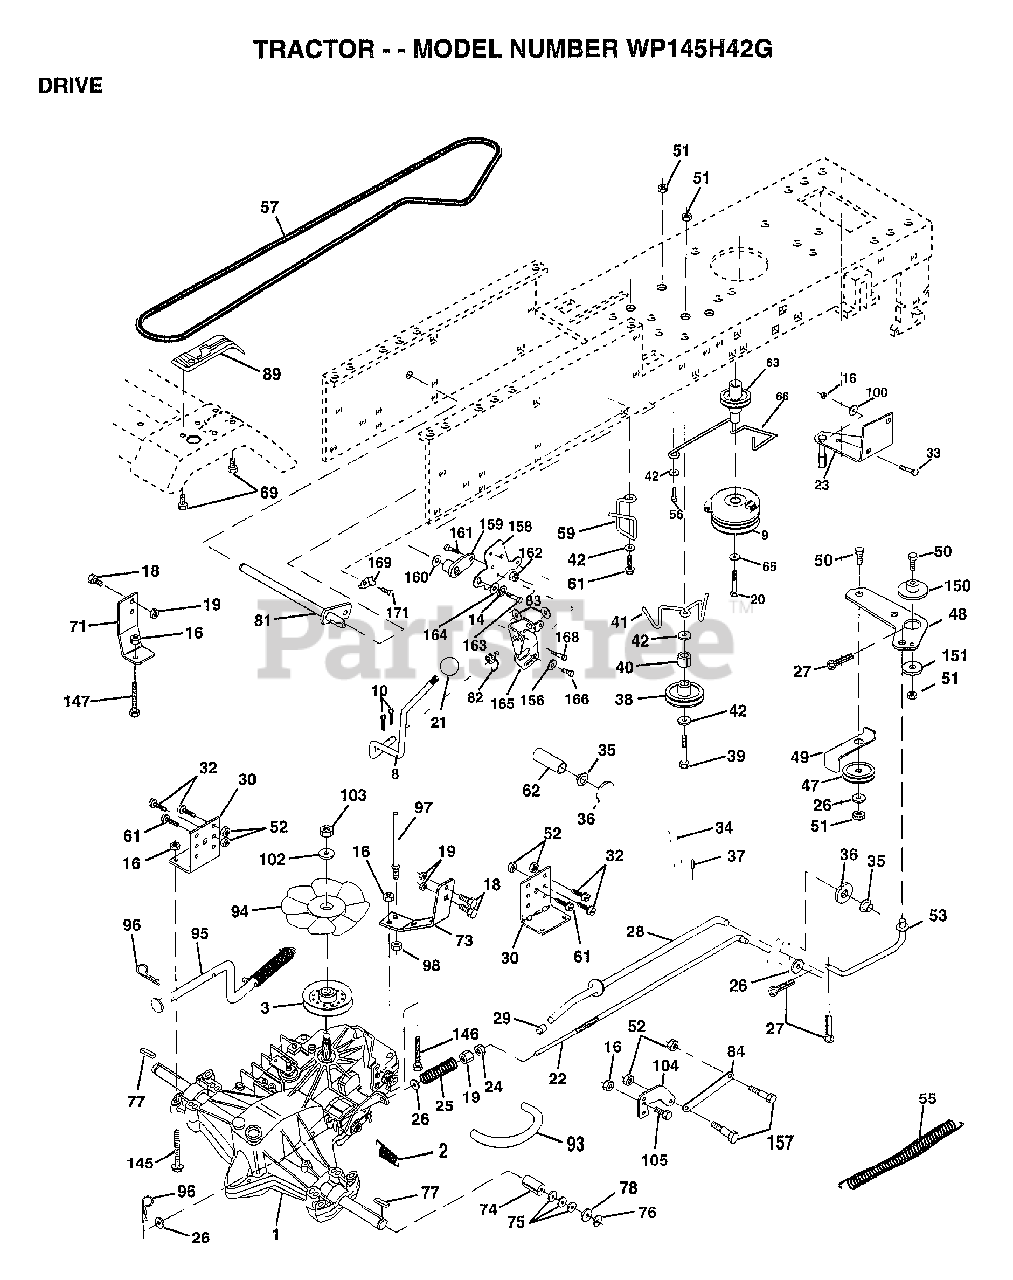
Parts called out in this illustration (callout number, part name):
2	SPRING RET BRAKE
3	PULLEY.TRANSAXLE
8	ROD.SHIFT.FENDER.ADJ.LT.CRD
9	CLUTCH.ELECT.EVX.
10	PIN COTTER 1/8
14	LOCKWASHER
16	NUT
18	BOLT
19	NUT
20	BOLT.7/16-20X4.25
21	KNOB T (1/2-HOLE)
22	ROD.BRAKE.HYDRO.
23	BRACKET.CLUT.MTG.
24	NUT
25	SPRING ROD LT
26	WASHER
27	COTTER PIN
28	ROD.BRAKE.PARK.LT
29	PLUNGER CAP T
30	TRANSAXLE MTG BKT
32	BOLT
33	BOLT
34	SHAFT ASM-PEDAL F
35	NYLON BEARING
36	WASHER LT
38	FLAT IDLER PULLEY
39	BOLT
40	SPACER T
41	"KEEPER,BELT.IDLER FLAT"
42	WASHER
48	BELLCRANK.CLUTCH
49	RETAIN BELT
53	"LINK, CLUTCH T"
55	"SPRING, RETURN LT"
57	"BELT.GD DRV 82"""
59	KEEPER BELT CNTSP
61	SCREW
62	PEDAL COVER T
63	PULLEY.CLUTCH.EVX
65	LOCKWASHER
66	KEEPER-BELT
69	SCREW HEXWSH H-L
71	STRAP TORQ LH HYD
73	"STRAP-TORQUE,RH"
74	SPACER SPLIT
75	WASHER
76	E-RING LT
77	SQUARE KEY
78	WASHER
81	SHAFT.ASM.CROSS
82	"SPRING,TORSION"
83	WASHER
84	LINK.TRANSAXLE.LT/YT
89	CONSOLE.SHIFT.LT
93	"LINE FUEL HYD 4"""
94	"FAN 7"" HYDRO"
96	RETAINER M
97	BOLT KEEPER RH
98	NUT
100	WASHER M
102	WASHER BELLEVILLE
104	ARM CONTROL HYDRO
105	SCREW CAP 5/16-18
145	BOLT.HEX.FLGHD
146	BOLT.HEX.FLGHD.
147	BOLT.HEX.FLGHD
150	BUSHING.BELLCRANK.GRD.DR
151	WASHER
156	WASHER.SRRTD.5/16
157	"BOLT,SHOULDER"
158	BRKT.SHIFT.MOUNT
159	HUB.SHIFT
160	WASHER
161	BOLT T
164	WASHER.5/8X.281X10GA
165	BRKT.PIVOT.LEVER
166	SCREW.5/16-18X5/8
168	BOLT.SHOULDER.5/16-18X.561
169	PLATE.FASTENING
171	SCREW LT
